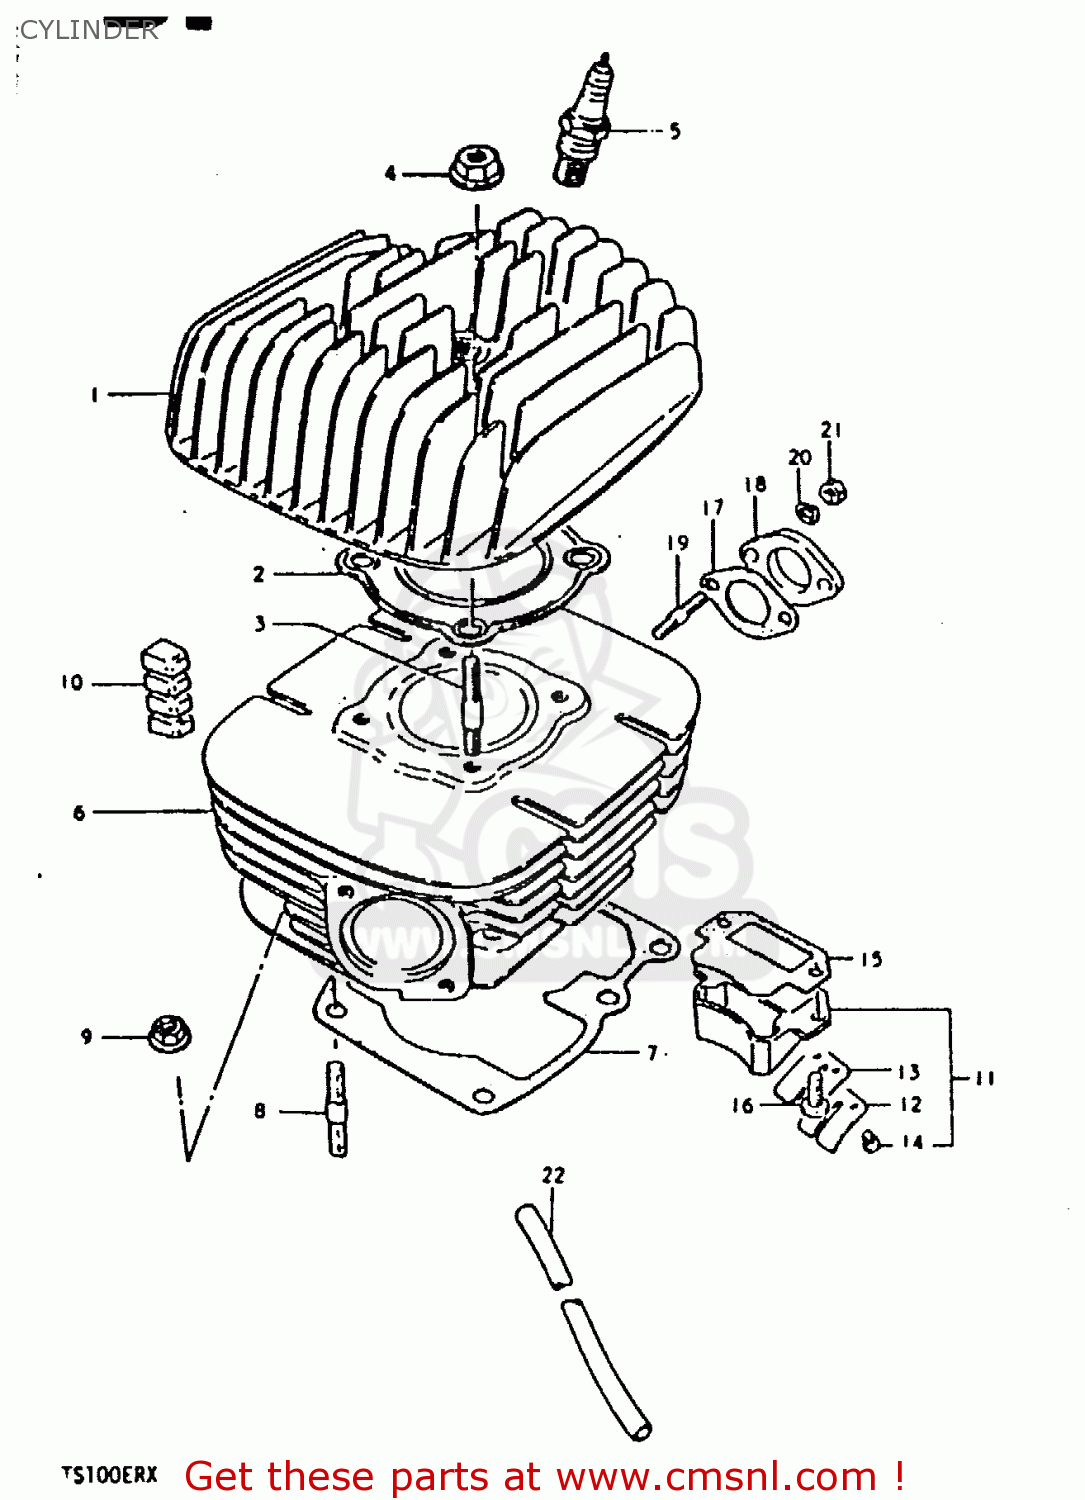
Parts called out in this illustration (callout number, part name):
1	HEAD,CYLINDER
2	GASKET,CYLINDER HEAD (MCA)
3	STUD BOLT
4	NUT
5	SPARK PLUG
6	CYLINDER
7	GASKET,CYLINDER (MCA)
8	STUD 8X25
9	NUT
10	PAD,CYLINDER
11	VALVE ASSEMBLY,REED
12	STOPPER,REED VALVE
13	VALVE,REED
14	SCREW,REED VALVE
15	GASKET,REED VALVE (MCA)
16	SCREW
17	GASKET,CARBURETOR (MCA)
18	INSULATOR,CARBURETOR
19	STUD BOLT
20	LOCK WASHER
21	NUT
22	HOSE
